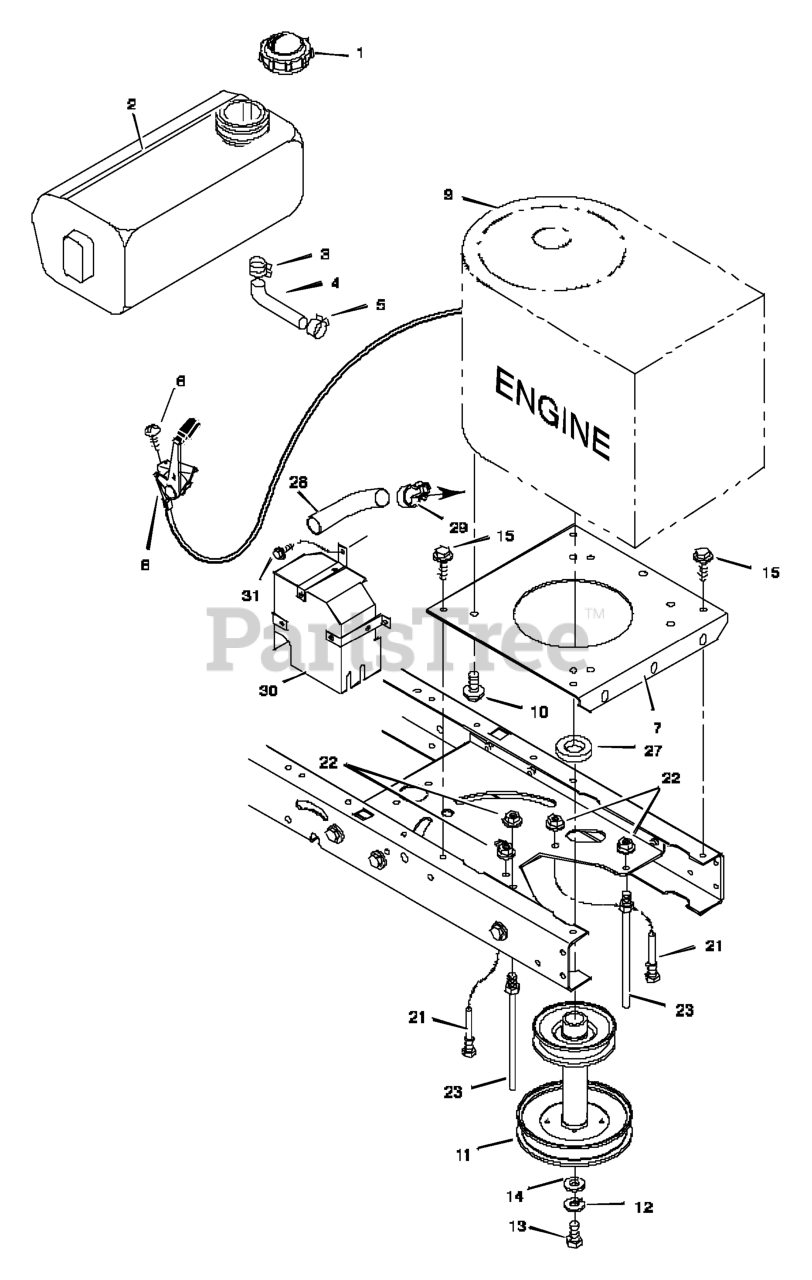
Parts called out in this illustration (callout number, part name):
1	Fuel Cap
2	Fuel Tank
3	Hose Clamp
4	Fuel Line
5	Hose Clamp
7	Plate, Engine
8	Throttle Control
9	Engine
10	Bolt, Engine Mount
11	Stack Pulley Assembly
12	Lockwasher
13	Bolt, Hex
21	Guide, Belt
22	Nut, Flange
23	Guide, Belt
28	Pipe, Exhaust
30	Shield, Heat
